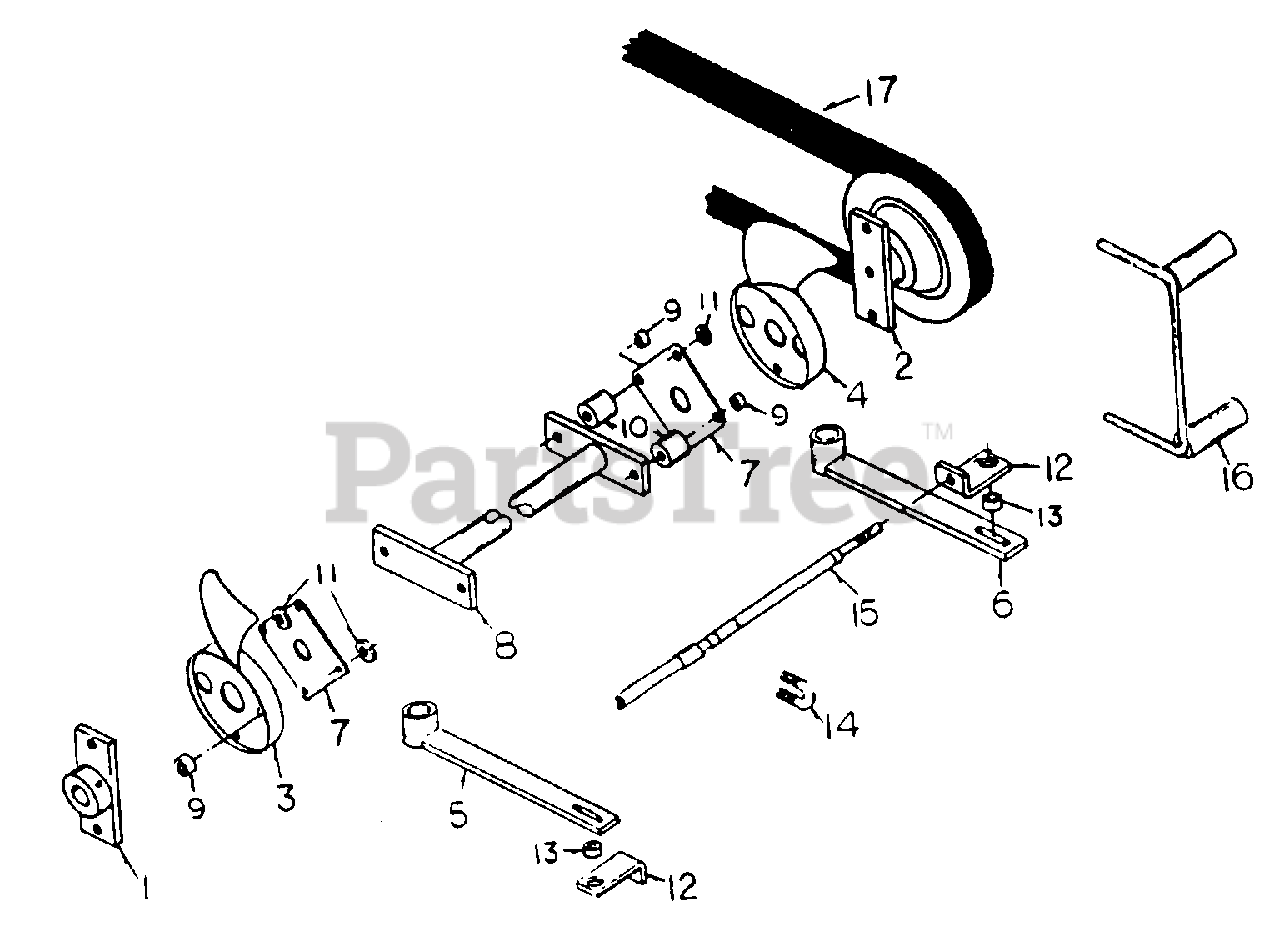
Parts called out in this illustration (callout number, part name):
1	Hub w/Drive Plate
2	Pulley w/Drive Plate
5	Transmission Arm, LH
6	Transmission Arm, RH
7	Drive Plate
8	Transmission Cross Shaft
11	Washer, 1/4", 10 Ga.
12	Steering Cable End
13	Bushing, Steering Lever
14	Steering Cable Clamp
15	Steering Cable
16	Belt Retainer, Transmission
